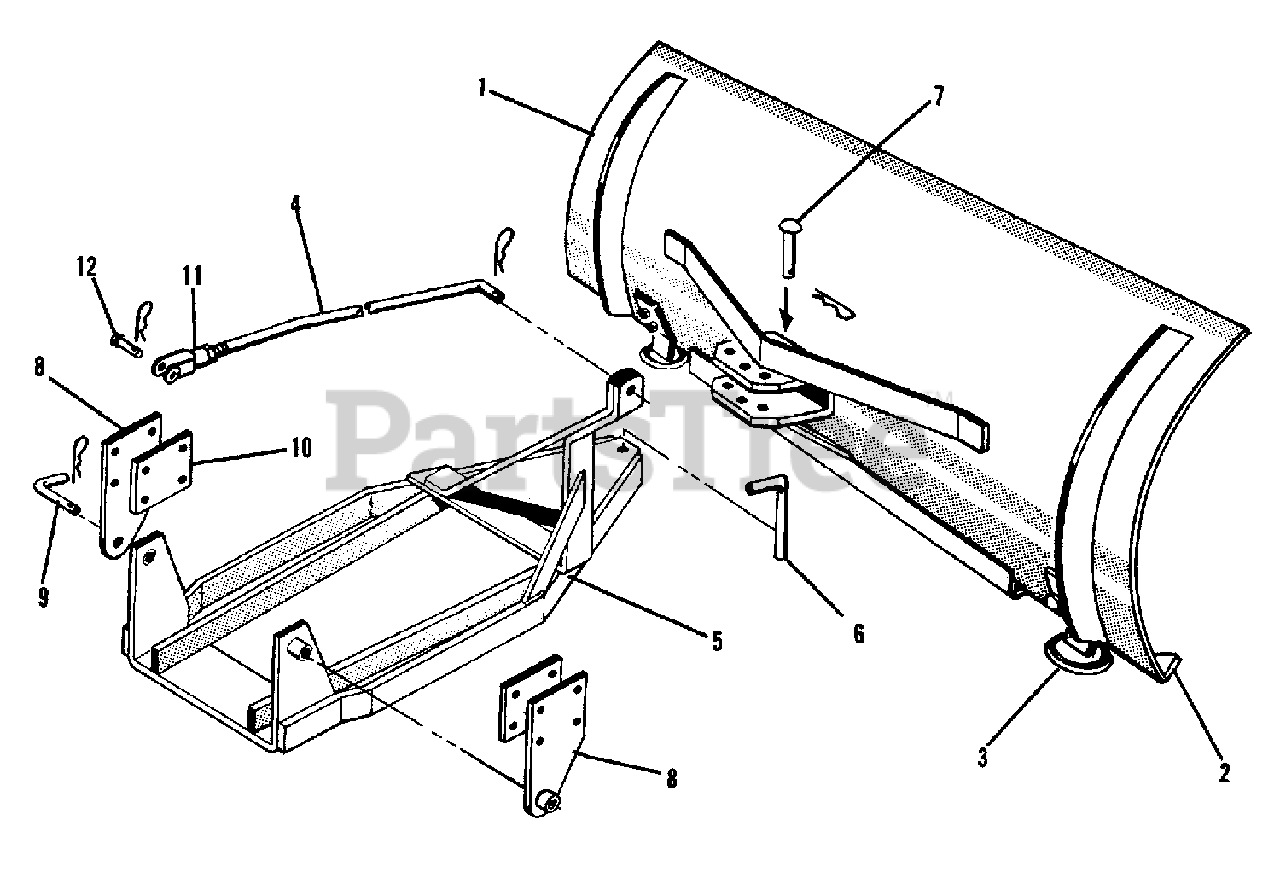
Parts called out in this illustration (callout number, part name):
1	BLADE ASSEMBLY, 42"
2	PLATE, Wear
2	BOLT, 3/8NC x 3/4
2	LOCKWASHER, 3/8
2	NUT, 3/8NC
3	SHOE ASSEMBLY, Blade
3	BOLT, 3/8NC x 1
3	LOCKWASHER, 3/8
3	NUT, 3/8NC
4	ROD, Lift
4	PIN, Quick
4	NUT, 1/2NF, Jam
5	FRAME ASSEMBLY, Push Bar
7	PIN, Quick
8	HITCH ASSEMBLY, L.H.
8	HITCH ASSEMBLY, R.H.
9	PIN, Hitch
9	PIN, Quick
10	PLATE, Nut
10	CAPSCREW, 3/8NC x 1
10	LOCKWASHER, 3/8
11	YOKE, Rod
12	PIN, Yoke
12	PIN, Quick
